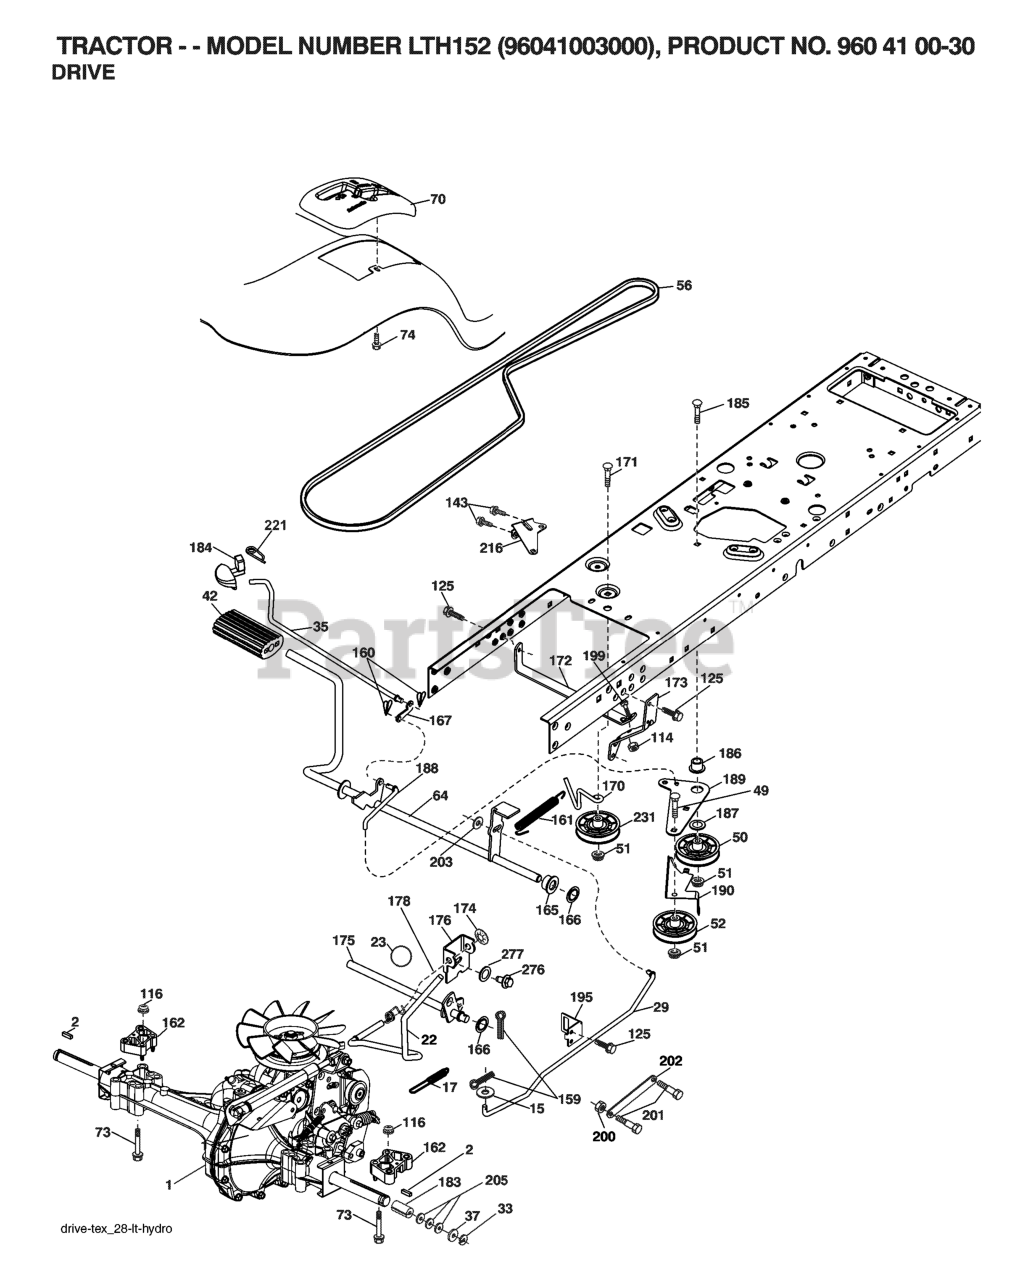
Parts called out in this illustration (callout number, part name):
2	SQUARE KEY
15	WASHER
17	SPRING.BRAKE.HG3000/3500
22	ROD.SHIFT.FENDER.TLT.2006
23	KNOB.DUCKHEAD.1/2
29	ROD.BRAKE.HG-0510
35	ROD.CNTRL.PARK.PREDATOR.LT.TEX
42	PEDAL COVER T
50	IDLER.FLAT.910.OFFSET
51	NUT LOCK FLG 3/8-16 UNC
52	IDLER.V-GROOVE.910.OFFSET
64	SHAFT.ASM.PEDAL.BRAKE.
70	CONSOLE SHIFT
74	SCREW.HI-LO.CONSOLE
114	NUT.71038.31-18.HEX.NYLOCK
116	NUT LOCK HEX FLANGE 5/16-18
125	SCREW
143	Screw 5/16-18 x 1/2 Hex, Self Tapping 5/16-18 x 1/2
159	COTTER PIN
160	RETAINER CLIP
161	SPRING.RETURN.CLUTCH.2006
162	SPACER.TRANSAXLE.18&22
165	BUSHING.SHAFT.BRAKE.HAND
166	NUT.PUSH.625.2006
167	LATCH.BRAKE.SPRING
170	KEEPER.V-IDLER.CENTER.
172	STRAP.TRQ.LH.FS.HG0510
173	STRAP TORQUE RH
174	NUT.PUSH.500.2006
175	SHAFT.ASM.SHFT.HG0510/
176	ARM.CLEVIS.ROD.SHIFT
178	SPRING.SHIFT.GT2006
183	SPACER AXLE
184	HANDLE.PARKNG BRK.PRED.LT.428
186	SPACER.RETAINER
187	WASHER 12/32X2X10GA
188	RP.LINK.CLUTCH.GROUND.DRIVE
189	BELLCRANK.GROUND.DRIVE.TEX.
190	KEEPER.BELLCRANK.DRIVE
195	BRKT.ROD.BRAKE.18/20/2
200	NUT.CENTERLOCK.5/16-
201	BOLT SHOULDER 5/16-18 UNC
202	LINK TRANS
203	WASHER
216	BRACKET.PULLEY.IDLER.W/TEX
221	RETAINER.SPRING.CLIP.H
231	IDLER.V-GROOVE.1.688.OFFSET
276	BOLT FIN HEX 7/16-14 X 1
277	WASHER SERRATED
